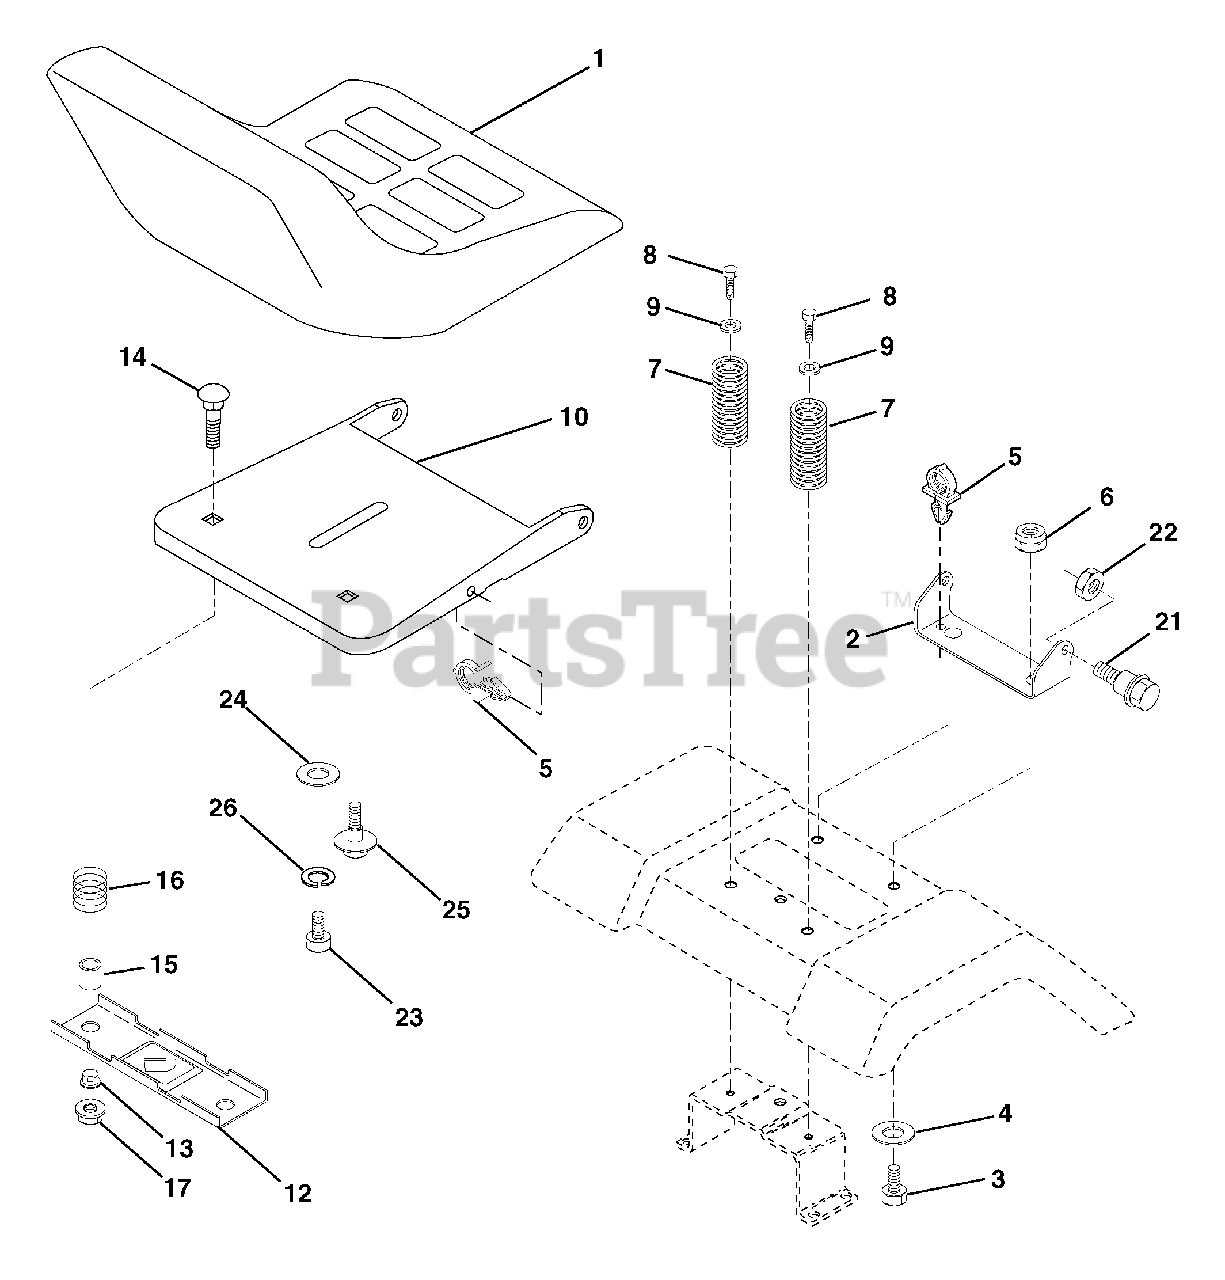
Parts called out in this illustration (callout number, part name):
1	Seat
2	Bracket Seat Pivot
3	Bolt Hex 3/8 - 16 x 1
4	Washer 13/32 x 1 x10 Ga.
5	Clip Push-In Hinged
6	Nut Lock Hex w/Ins 3/8 - 16
7	Spring Seat Cprsn 2 250 Blk Zi
8	Screw 3/8-16 x 1.5
9	Washer 13/32 x 1 x 14 Ga.
10	Pan Pnt Seat (Blk)
12	Bracket Pnt Mounting Switch
13	Bushing Snap Blk Nyl
14	Bolt Rdhd Sht Nk 1/4 - 20 x 1 -1/2
15	Spacer Split .28 x .96
16	Spring Cprsn
17	Nut Lock 1/4 Lge Flg
21	Bolt Shoulder 5/16-18 unc-2A
22	Nut Lock Hex w/Ins 5/16 - 18
23	Bolt Hex
24	Washer 17/32 x 1-3/16 x 12 Ga.
25	Bolt Shoulder 5/16-18 x .62
26	Washer Lock Hvy Hlcl Spr 1/2
